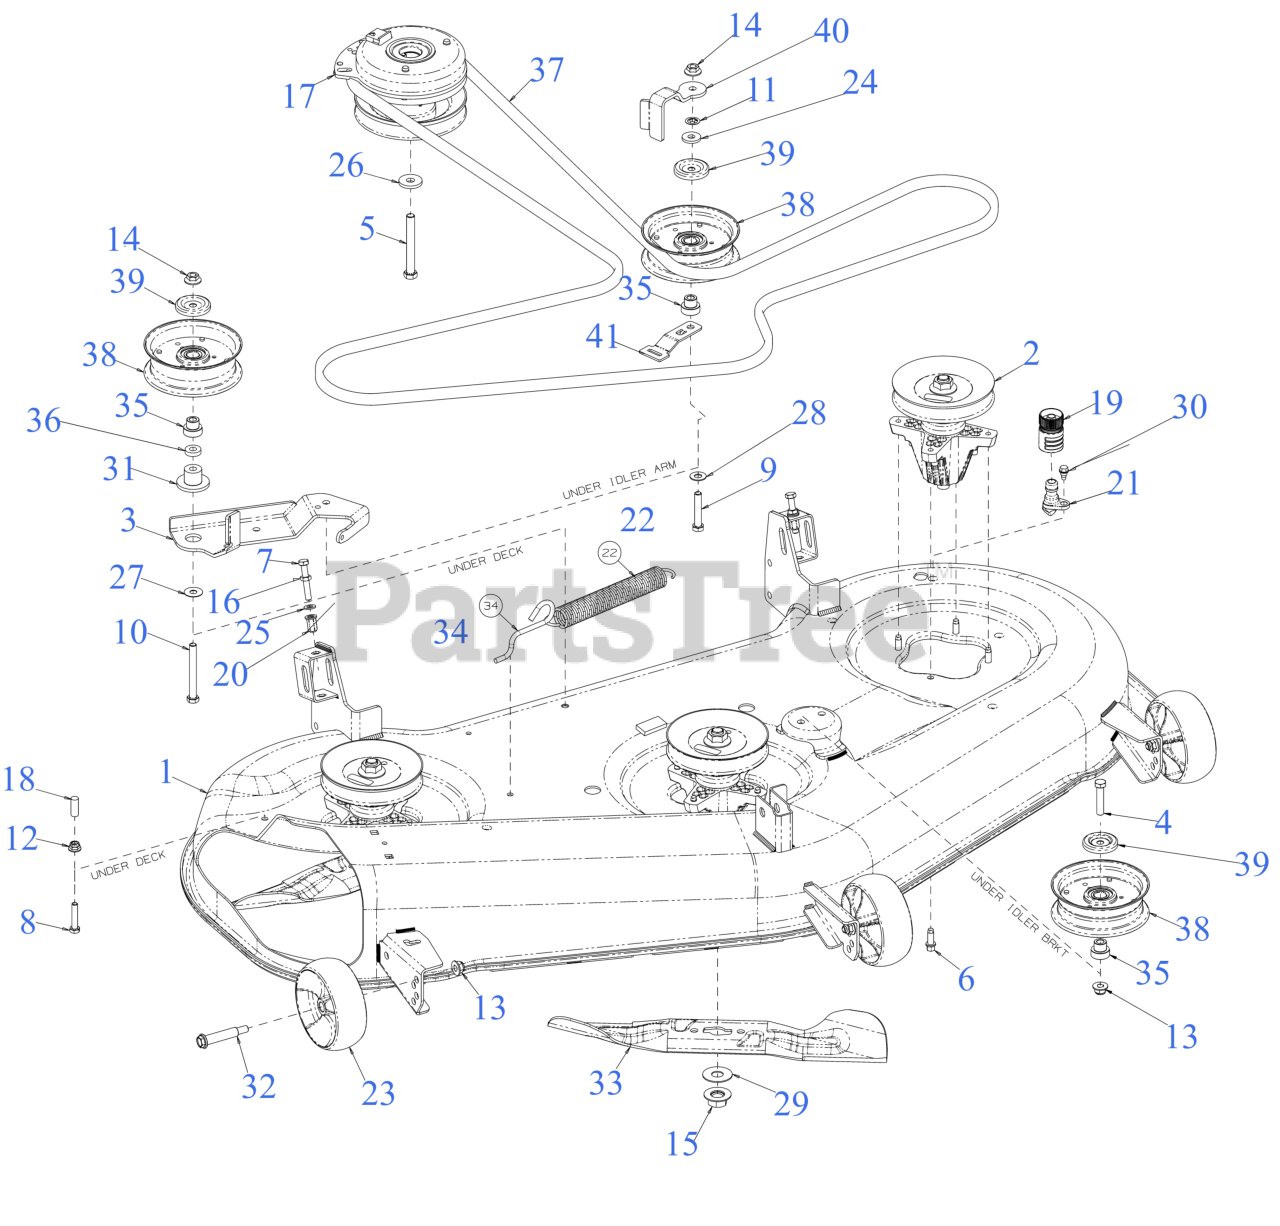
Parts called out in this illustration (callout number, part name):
1	54" DECK SHELL
2	SPINDLE ASSEMBLY
3	DECK IDLER BRACKET
4	HEX SCREW 3/8-16 x 1.75 GR5
5	SCREW 7/16-20 x 3.5 GR5
6	SCREW 5/16-18 x .875
7	SCREW-FULL THREAD 5/16-18 GR5
8	SCREW 5/16-18 x 1.5 LG
9	SCREW 3/8-16 x 2.0 GR 8
10	SCREW 3/8-16 x 3.25 GR8
11	PUSH NUT
12	FLANGE LOCK NUT 5/16-18
14	FLANGE LOCK NUT
15	HEX FLANGE NUT 5/8-18 GR5
16	HEX NUT
17	ELECTRIC PTO CLUTCH
18	VINYL CAP
19	WATER NOZZLE ADAPTER
20	NUT RIVET 5/16-18
21	DECK WASH NOZZLE
22	EXTENSION SPRING
23	DECK WHEEL (5.0 DIA x 1.875)
23	Cub Cadet 5" DECK WHEEL SET (06305A) (W/BOLT)
24	FLAT WASHER .385 x 1.00 x .135
25	FLAT WASHER
26	FLAT WASHER .445 x 1.248 x .170
27	FLAT WASHER
28	FLAT WASHER .401X.88
29	FLAT WASHER .635X1.585X.062 HDN
30	SHOULDER SCREW 1/4-20 x .50
31	SHOULDER SPACER
32	SHOULDER BOLT (.50 X 2.0 x 3/8 -16)
33	18.611" BLADE (2IN1) (S SHAPE CENTER HOLE)
33	Cub Cadet 54" HI LIFT BLADE SET (S SHAPE CENTER HOLE) (-05086)
33	Troy-Bilt 54" HI LIFT BLADE SET (S SHAPE CENTER HOLE)
33	18.611" XTREME BLADE (2IN1) (S SHAPE CENTER HOLE)
33	Cub Cadet 54" XTREME BLADE SET (S SHAPE CENTER HOLE) (-05086-X)
33	Troy-Bilt 54" XTREME BLADE SET (S SHAPE CENTER HOLE)
33	18.611" LOW LIFT (S SHAPE CENTER HOLE)
33	Cub Cadet 54" LOW LIFT BLADE SET (S SHAPE CENTER HOLE) (-05086-L)
33	Troy-Bilt 54" LOW LIFT BLADE SET (S SHAPE CENTER HOLE)
34	DECK SPRING HOOK
35	SHOULDER SPACER
37	V-BELT B SEC x 148.25
37	Cub Cadet 54" DECK DRIVE BELT
38	IDLER PULLEY 4.50" DIA
39	IDLER PULLEY CAP
40	BELT KEEPER
